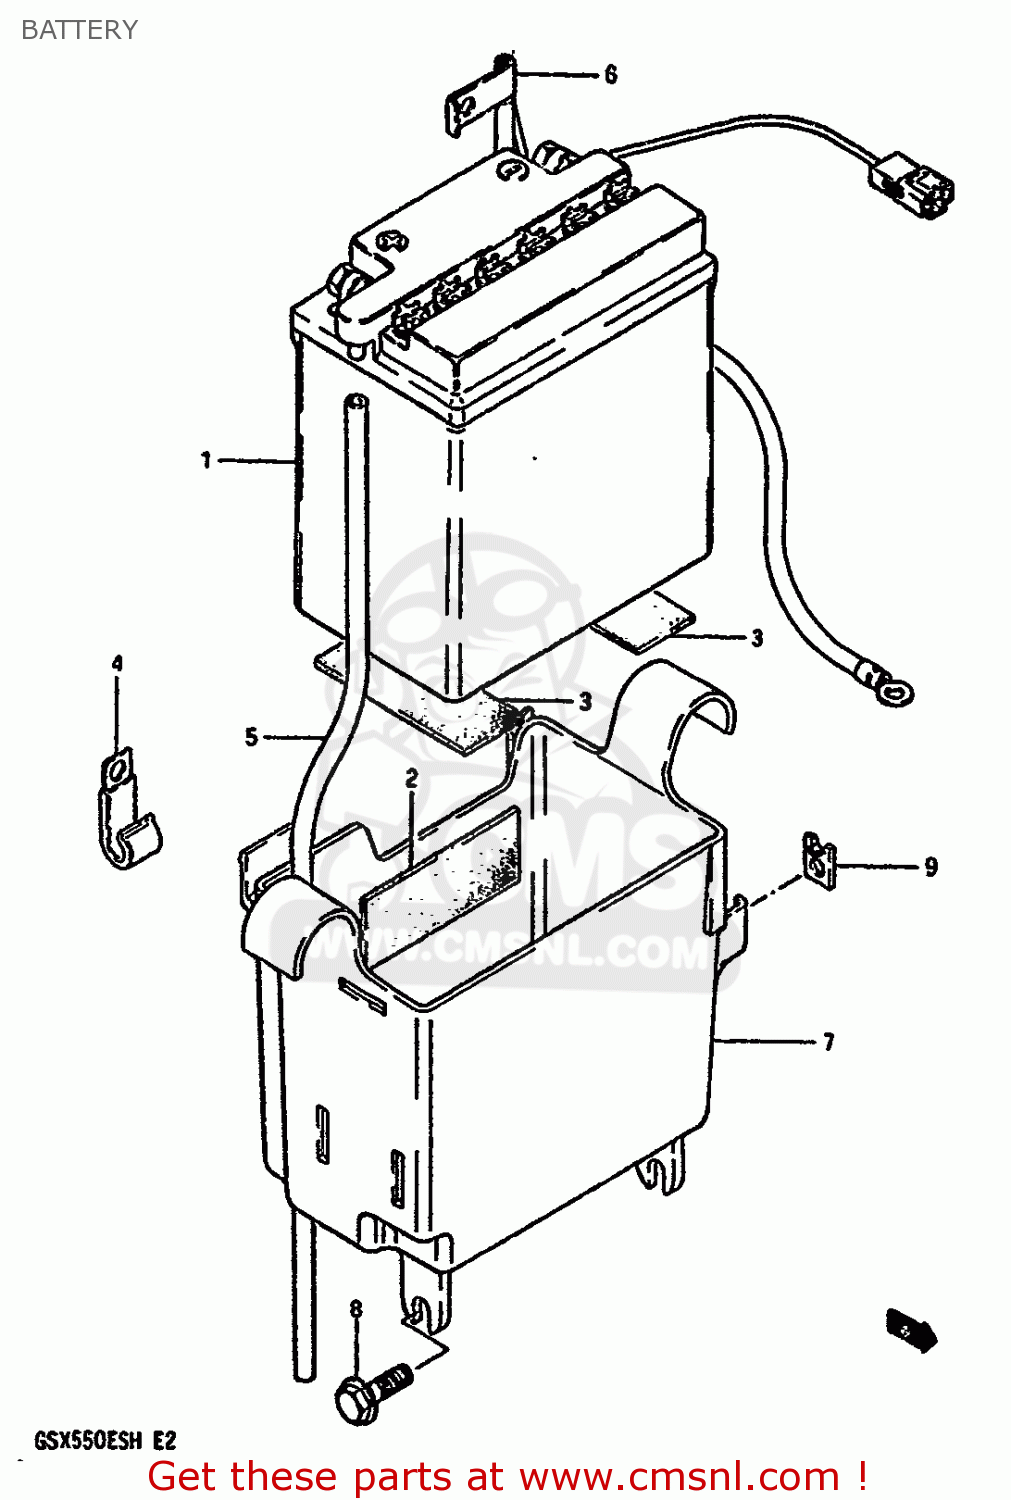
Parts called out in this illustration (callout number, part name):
1	BATTERY(YB10L-B,12V12AH)
2	PROTECTOR(30X80X2)
3	PROTECTOR,20X9
4	CLAMP
5	HOSE,BATTERY EXHAUST
6	WIRE,BATTERY MINUS LEAD
7	HOLDER,BATTERY
8	BOLT
9	WASHER,IGNITER
